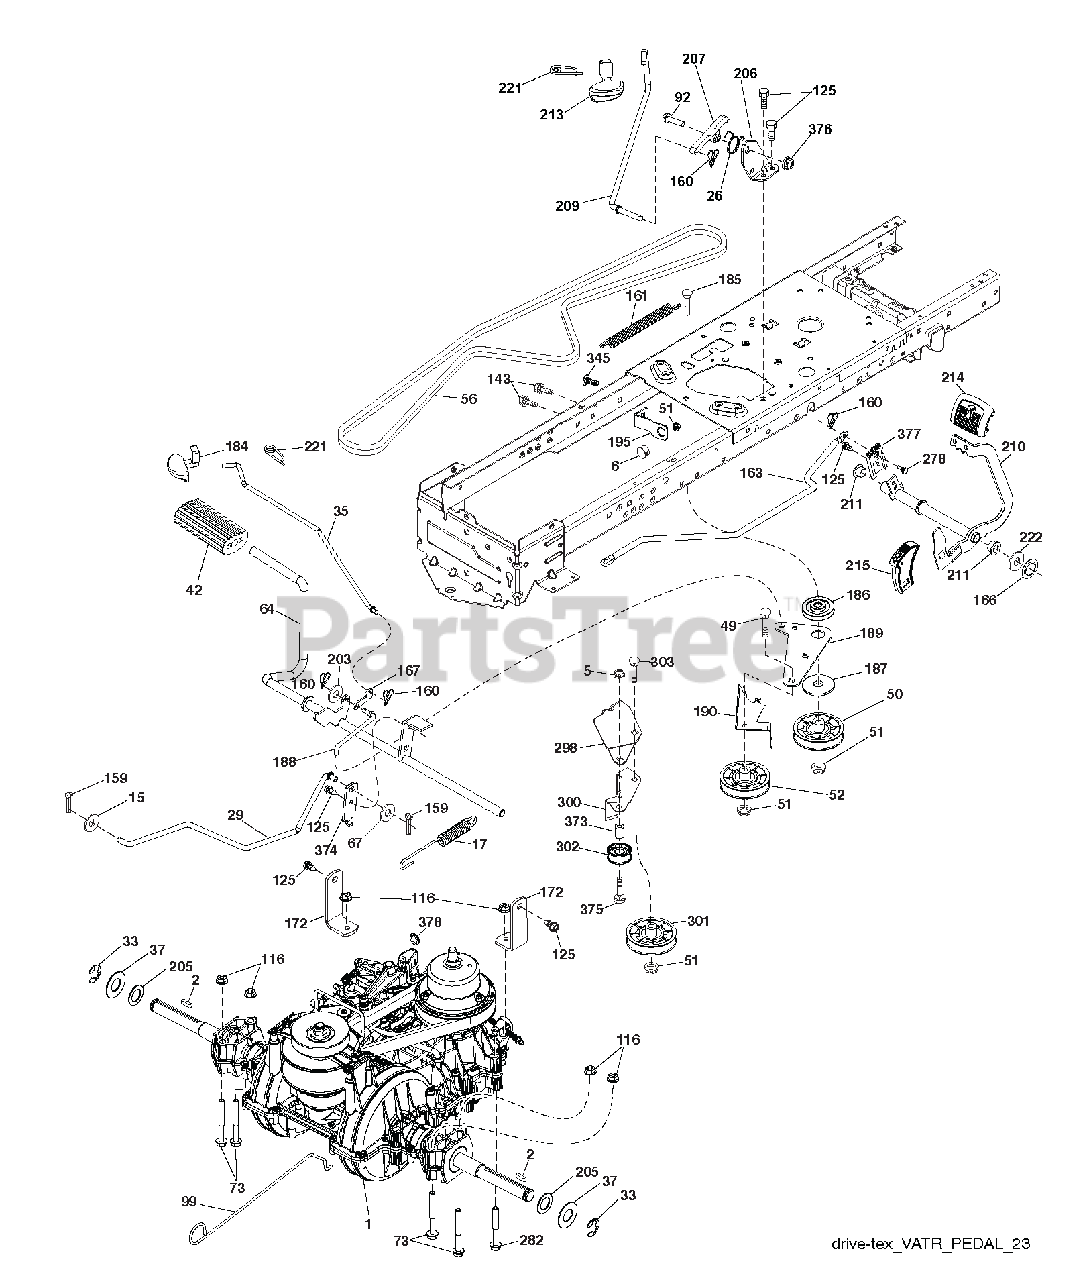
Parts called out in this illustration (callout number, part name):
1	TRANSMISSION, GENTRANS VATR.
1	(580486201) (ORDER PARTS FROM
1	TRANSAXLE MANUFACTURER.)
2	KEY.SQUARE.2.0 X .1845/.1865
5	Nut, Hex, Crownlock 3/8-16
6	Bushing Snap Nyl Blk Fuel Line
15	WASHER.13/32 X 13/16 X 16 GA.
17	SPRING.BRAKE.K46.GREEN
26	SPRING.RETURN.CRUISE
29	ROD.BRAKE
33	E-RING.#5133-75
35	ROD.BRAKE.PARKING.LT.TEX
37	WASHER.HARDEN..793 X 1.637X060
42	COVER PEDAL BLK ROUND
49	BOLT.RDHD.3/8-16UNCX1-3/4.GR5
50	IDLER.FLAT.910"OFFSET
51	Nut, Hex, Flangelock 3/8-16
52	IDLER.V-GROOVE.910"OFFSET
56	BELT.DRIVE.100.97"
64	SHAFT ASM. PEDAL BRAKE
67	Washer 13/32 x 13/16 x 12 Ga.
73	BOLT.HEX.FLGHD.5/16-18.GR.5
92	Bolt, Hex Head 5/16-18 x 1-1/4
99	ROD.BYPASS
116	Nut, Lock Hex Flange 5/16-18 u
125	SCREW.5/16-18X3/4.SMGML.TAP/BL
143	SCREW.THDROL.5/16-18 X 1/2TYTT
159	PIN.COTTER.1/8 X 3/4.CAD.
160	RETAINER.CLIP(M).DIA.290
161	SPRING.RETURN.CLUTCH.6.75
163	ROD CONTROL PEDAL
166	NUT PUSH .625
167	LATCH.BRAKE.PARKING
172	STRAP TORQUE VARIATOR
184	HANDLE.PARKNG.BRAKE.LT.TEX.667
185	BOLT.RDHD.3/8-16UNC X2-3/4 GR5
186	SPACER.RETAINER
187	WASHER.13/32 X 2 X 10 GA.
188	LINK.CLUTCH.GROUND DRIVE
189	BELLCRANK.GROUNDRIVE.NSTG/NSTL
190	KEEPER.BELLCRANK.DRIVE.GROUND
195	BRACKET.BRAKE
203	Washer 11/32 x 11/16 x 16 Ga.
205	WASHER.25/32 X 1-5/8 X 16GA.
206	BRACKET MOUNT LATCH CRUISE
207	LATCH CONTROL CRUISE
209	ROD.CONTROL.CRUISE
210	WELDMENT PEDAL
211	BEARING.NYLON.BLK..629 ID.
213	KNOB.CONTROL.CRUISE
214	PAD PEDAL FORWARD
215	CAP PEDAL REVERSE
221	RETAINER.SPRING.CLIP.HANDLE
222	WASHER.21/32X1-1/4.10GA.N/PLTD
278	BOLT CRUISE VARIATOR
282	BOLT.HEX. 5/16-18 X 3 GR. 5
298	Bracket Mount Idler
300	Keeper Idler Rear
301	Pulley Idler V-Groove
302	PULLEY,IDLER.FLAT
303	Bolt RDHD SQNK 3/8-16 x 2-1/4
345	Bolt Rdhd Sht Sqnk 3/8-16 x 3/
373	SPACER.IDLER
374	ARM.BRAKE.CONTROL
375	BOLT.HEX.HS.3/8-16.UNCX2-1/4
376	Locknut, Hex 5/16-18
377	GEAR SECTOR CONTROL CRUISE
378	NUT PUSH
